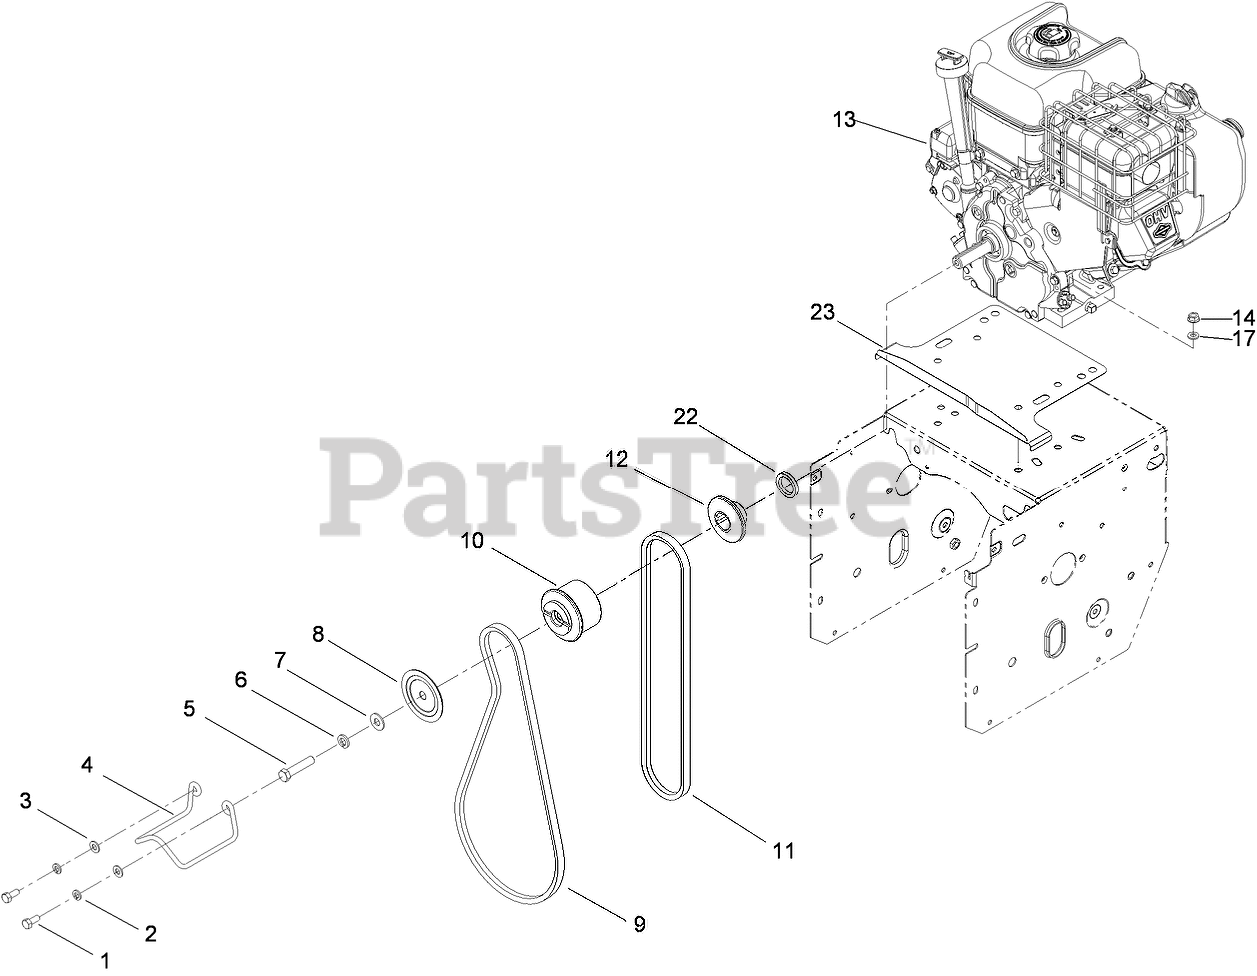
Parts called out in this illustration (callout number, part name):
1	SCREW-HH
2	WASHER-LOCK
3	WASHER-PLAIN
4	GUIDE-BELT
5	SCREW-HH
6	WASHER-LOCK
7	WASHER-FLAT
8	SHEAVE-HALF, IMPELLER
9	BELT-V
10	PULLEY-ENGINE, CENTER
11	V BELT-TRACTION
12	SHEAVE-HALF, TRACTION
14	NUT-HF
17	WASHER-FLAT
22	SPACER-HARDENED
23	SHIELD-DRIVE
